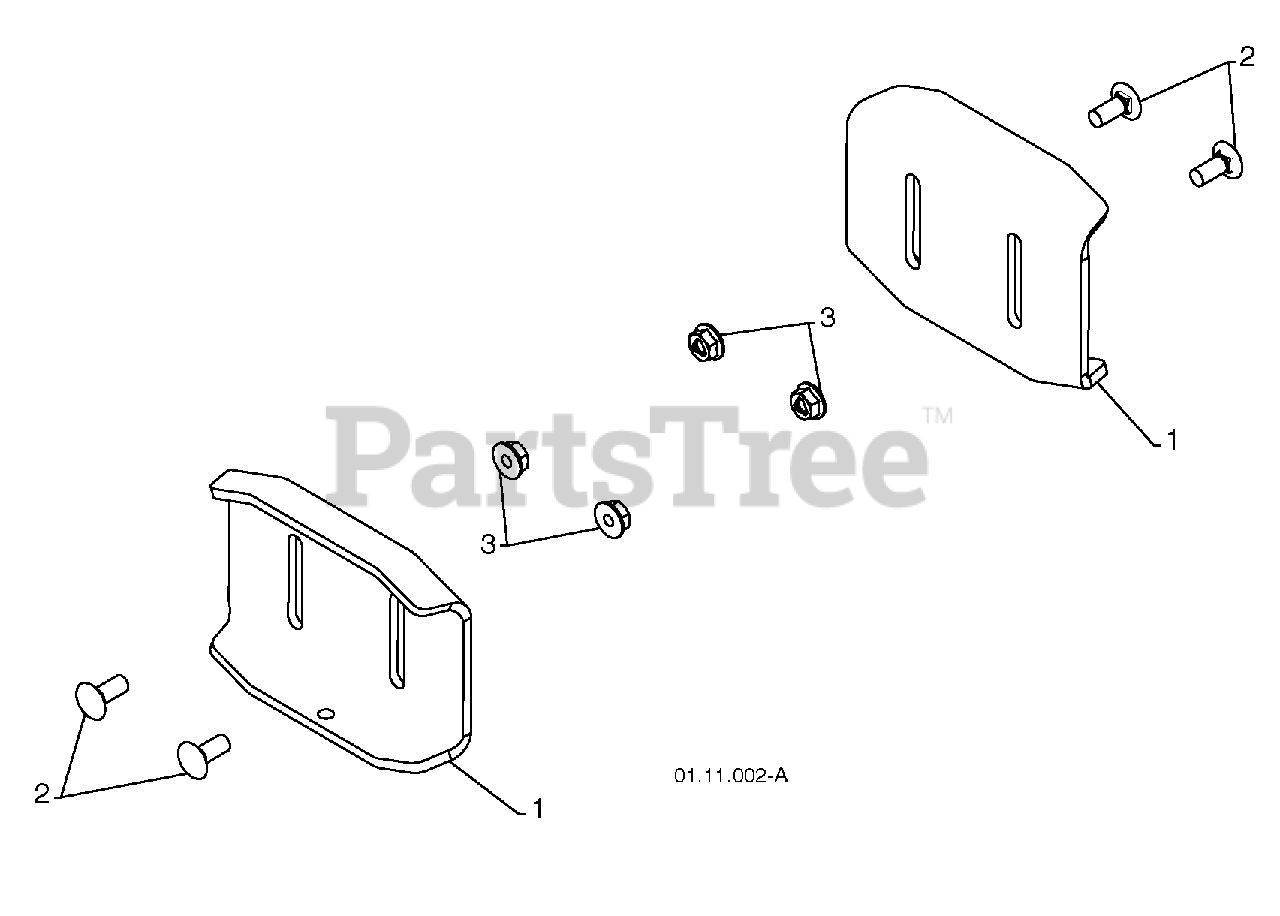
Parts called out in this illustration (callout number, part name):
1	SKID PLATE
2	CARRIAGE BOLT 5/16-18 X .750
3	NUT 5/16-18
